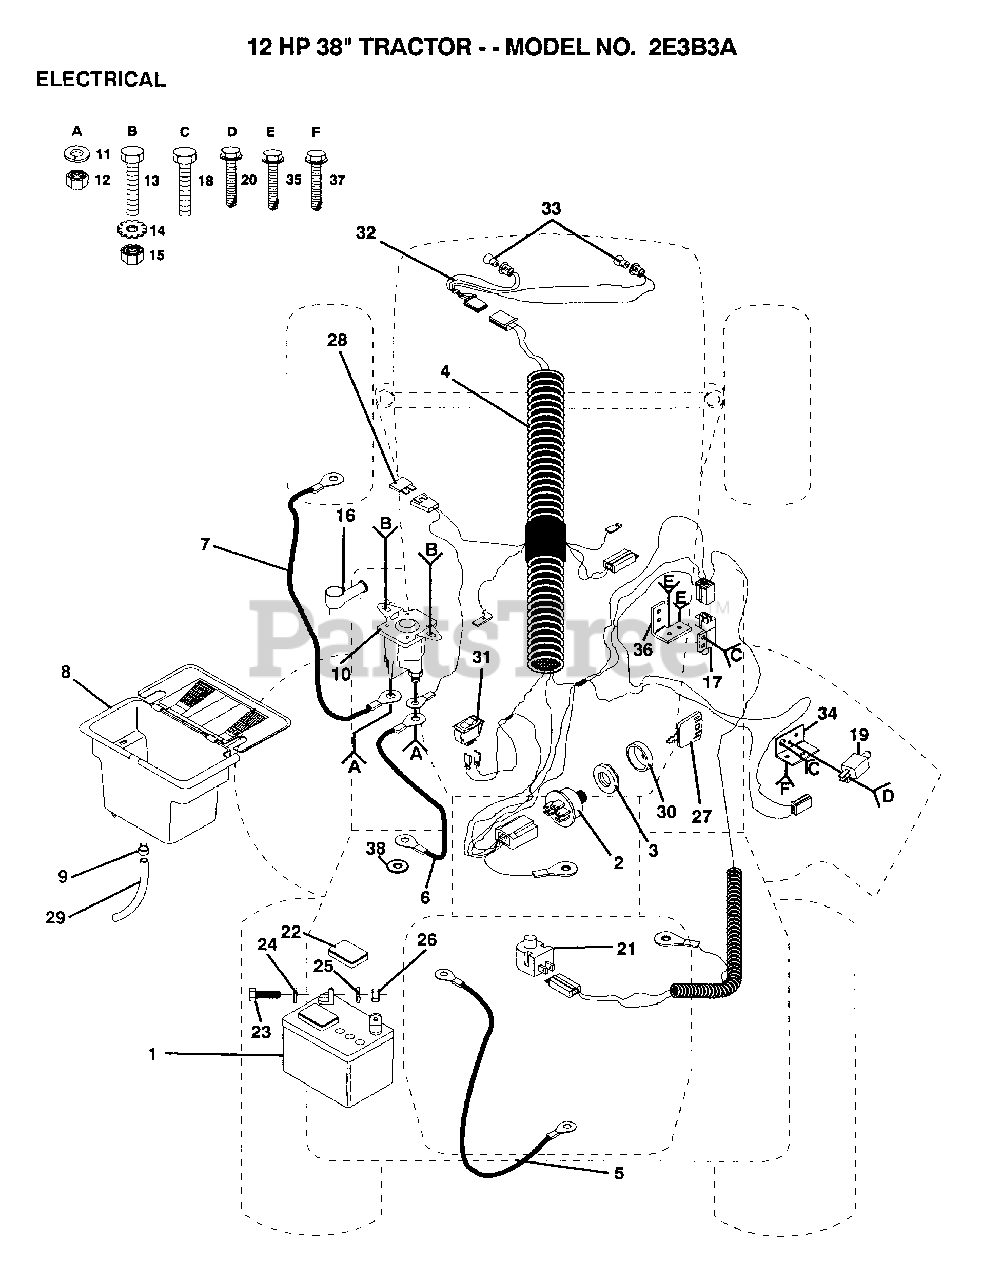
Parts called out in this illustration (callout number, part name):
3	NUT IGNITION
4	IGN HARNESS
5	CABLE T
7	"CABLE T, BATTERY"
9	HOSE CLAMP T
12	NUT
13	BOLT
15	NUT
17	SWITCH INTERLOCKT
18	SCREW
19	SWITCH-INTER. GT
20	SCREW
21	SWITCH SEAT
22	"CAP,BATTERY "
23	BOLT LT
24	WASHER
25	LOCKWASHER
28	FUSE HYT
29	TUBE T
31	SWITCH LT
32	"HARNESS,LIGHT SOC"
33	HEADLAMP BULB
34	BRACKET LT
35	SCREW
36	SWITCH BRACKET
37	SCREW
38	LOCKWASHER
